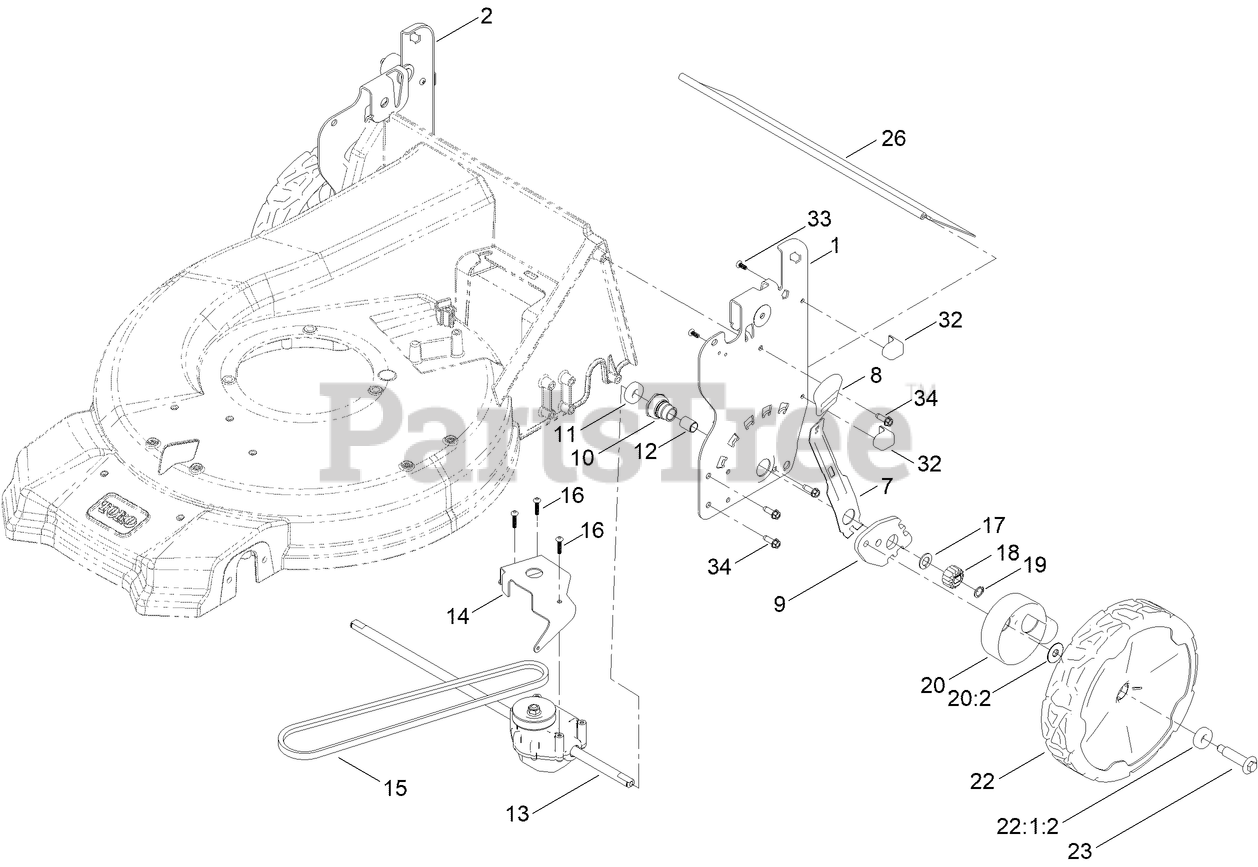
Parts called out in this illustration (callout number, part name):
1	PLATE-HOC, LH
2	PLATE-HOC, RH (2 HOLE)
7	ARM-SPRING
8	KNOB-HOC
9	ARM-PIVOT, REAR
10	RETAINER-BUSHING, HOC
11	BEARING-WHEEL
12	BUSHING-SLEEVE
13	TRANSMISSION-RWD, 5.25:1
14	BRACKET-TRANS, RWD HI
15	BELT-V
16	SCREW-PLASTITE
17	WASHER-THRUST
18	GEAR-PINION, 15T
19	RING-RETAINING
20	ASM-COVER, GEAR
20:2	WASHER-STEPPED
22	ASM-9.65" WHEEL, GEARED
22:1	ASM-WHEEL, 9.65" (BEARINGS)
22:1:2	BEARING-WHEEL
23	WHEEL BOLT
26	SHIELD-TRAILING
32	PAD-SMART STOW
33	SCREW-PPH
34	SCREW-HWHTF
